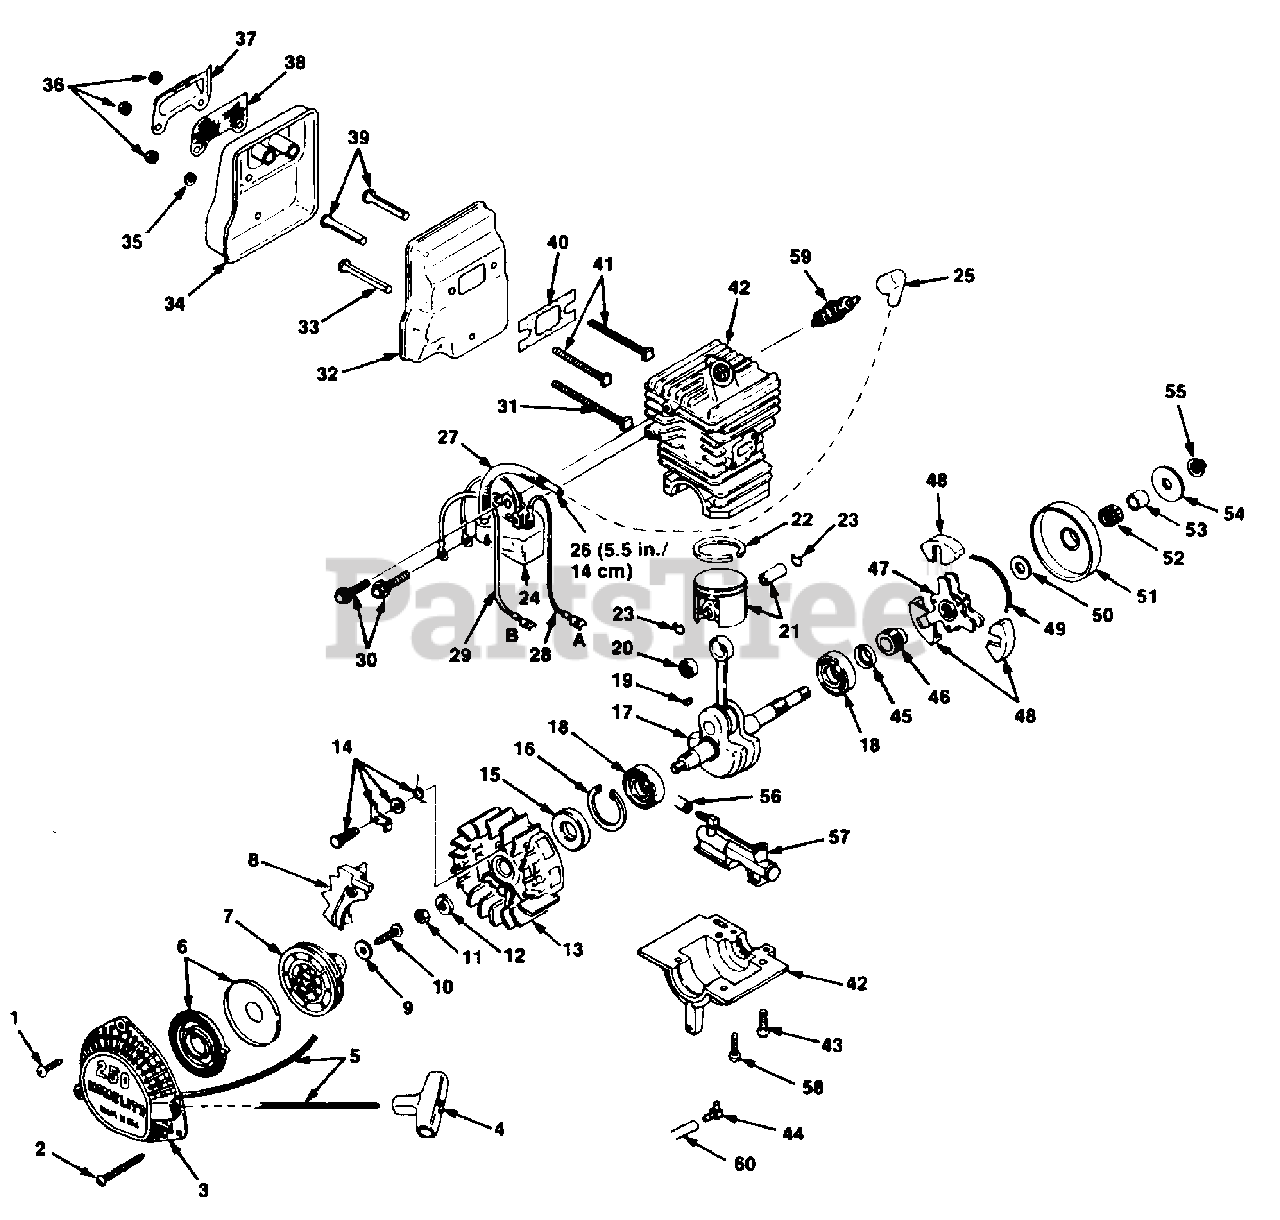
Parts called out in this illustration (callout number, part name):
1	SCREW- (8-16 x 5/8")
2	SCREW- (8-16 x 2")
3	STARTER HOUSING w/Decal
4	GRIP-Starter
5	ROPE
6	SPRING & CONTAINER
8	HOUSING- Starter side
9	WASHER- Retainer
10	SCREW- Thd. forming (10-24 x 5/8")
11	NUT- Jam
12	WASHER- Lock (3/8")
13	ROTOR & STARTER PAWL ASSY.
14	STARTER PAWL
15	SEAL- Shaft
16	RING- Retaining
17	CRANKSHAFT
18	BEARING- Ball
19	KEY- Woodruff
20	BEARING- Roller
21	PISTON & PIN
22	RING- Piston
23	RING- Retainer
24	MODULE- Ignition
25	BOOT- Spark plug
26	LEAD- Hi Tension
27	INSULATOR- Lead
28	WIRE- Ignition
29	WIRE- Ground
30	SCREW- (10-24 x 7/8")
31	SCREW- Square hd. (10-32 x 2 1/2")
32	BODY- Muffler
33	SPACER- Muffler
34	COVER- Muffler
35	WASHER- Flat #10
36	NUT- Hex 10-32
37	COVER- Exhaust
38	SCREEN- Spark arrestor
39	SPACER- Muffler
40	GASKET- Muffler
41	SCREW- (10-32 x 2 1/4")
42	CYLINDER & CRANKCASE
43	SCREW-Hex hd.
44	FITTING- Oil tube
45	SEAL- Crankshaft
46	WORM- Left hand
47	SPIDER- Clutch
48	SHOE- Clutch
49	SPRING- Clutch
50	WASHER- Thrust
51	SPROCKET & DRUM
52	BEARING- Needle
53	RACE- Inner
54	WASHER- Thrust
55	NUT- Hex Lock 3/8-24
56	LINE- Oil
57	PUMP- Oil
58	SCREW
59	PLUG- Spark
60	TUBING- Rubber
